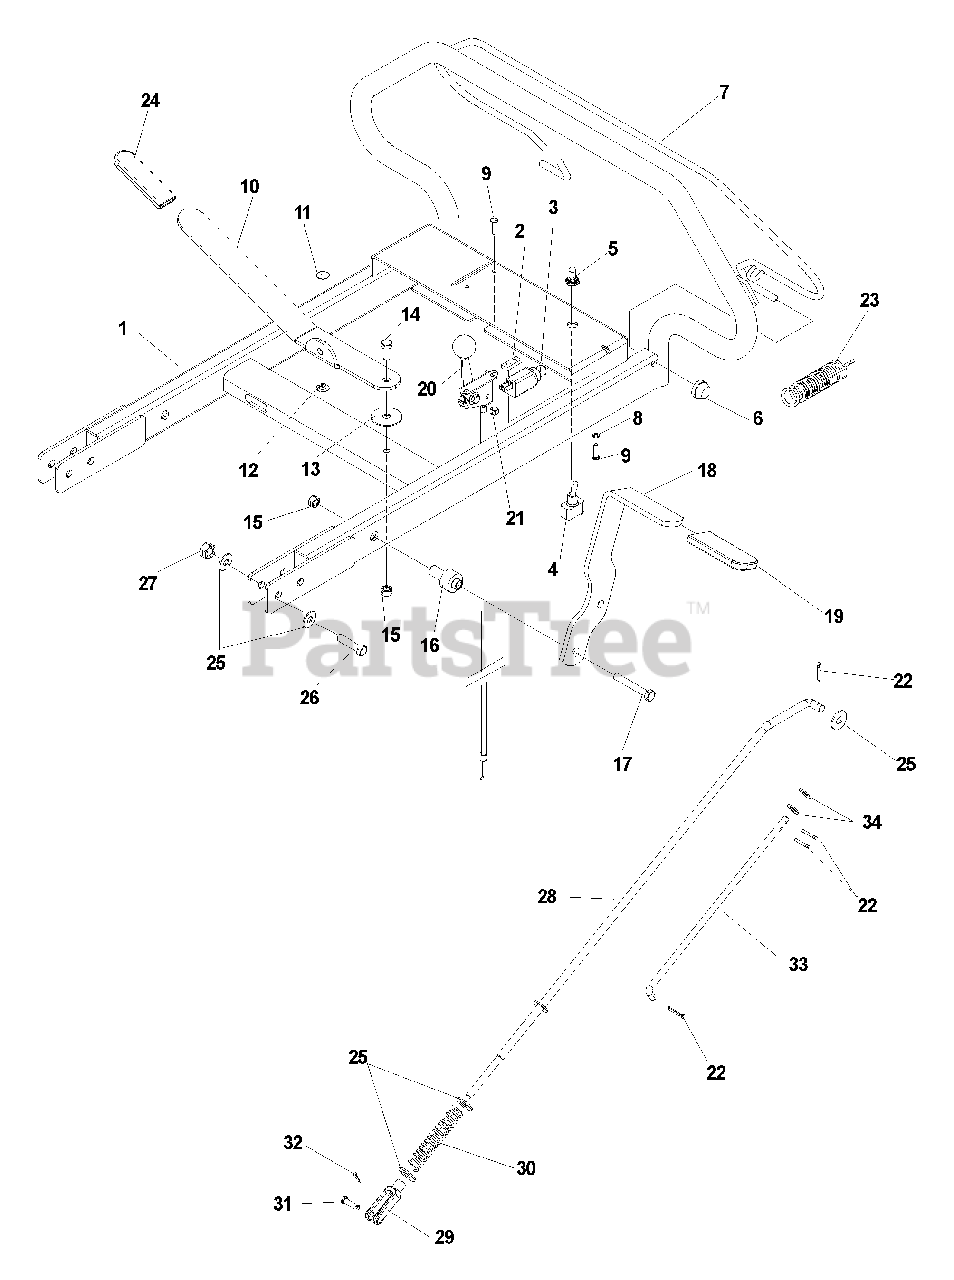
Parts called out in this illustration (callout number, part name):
1	HANDLE W/DECAL, UPPER
2	PLATE, TAPPED
3	SWITCH, NC PLUNGER TYPE
4	SWITCH, TOGGLE
5	BOOT, TOGGLE SWITCH
6	NUT 5/16, PUSH CAP
7	BAIL KIT
8	LOCKWASHER 5/16
9	SCREW #10-24 X 3/4, SLTD RD
10	HANDLE, POSITION ADJ.
11	RIVET, SNAP-MALE HALF
12	RIVET, SNAP-FEMALE HALF
13	WASHER, FRICTION
14	HCS 5/16-18 X 3/4, GR5
15	NUT 5/16C, CENTER LOCK
17	HCS 5/16-18 X 2 1/4, GR5
18	HANDLE, WHEEL BRAKE
19	GRIP, PARK BRAKE
20	THROTTLE CONTROL W/KNOB
21	NUT #10-24, NYLOC
22	COTTER PIN
24	GRIP, BLACK VINYL
25	WASHER 3/8, FLAT
26	HCS 3/8-16 X 2, GR5
27	NUT 3/8C, CENTER LOCK
28	ROD, PARK BRAKE
29	YOKE, 3/8F
30	SPRING, COMPRESSION
31	PIN, CLEVIS 1/4 X 7/8
32	PIN, HAIR, 5/64 X 1 7/16
33	ROD, POSITION ADJUSTMENT
34	WASHER 5/16, SAE FLAT
